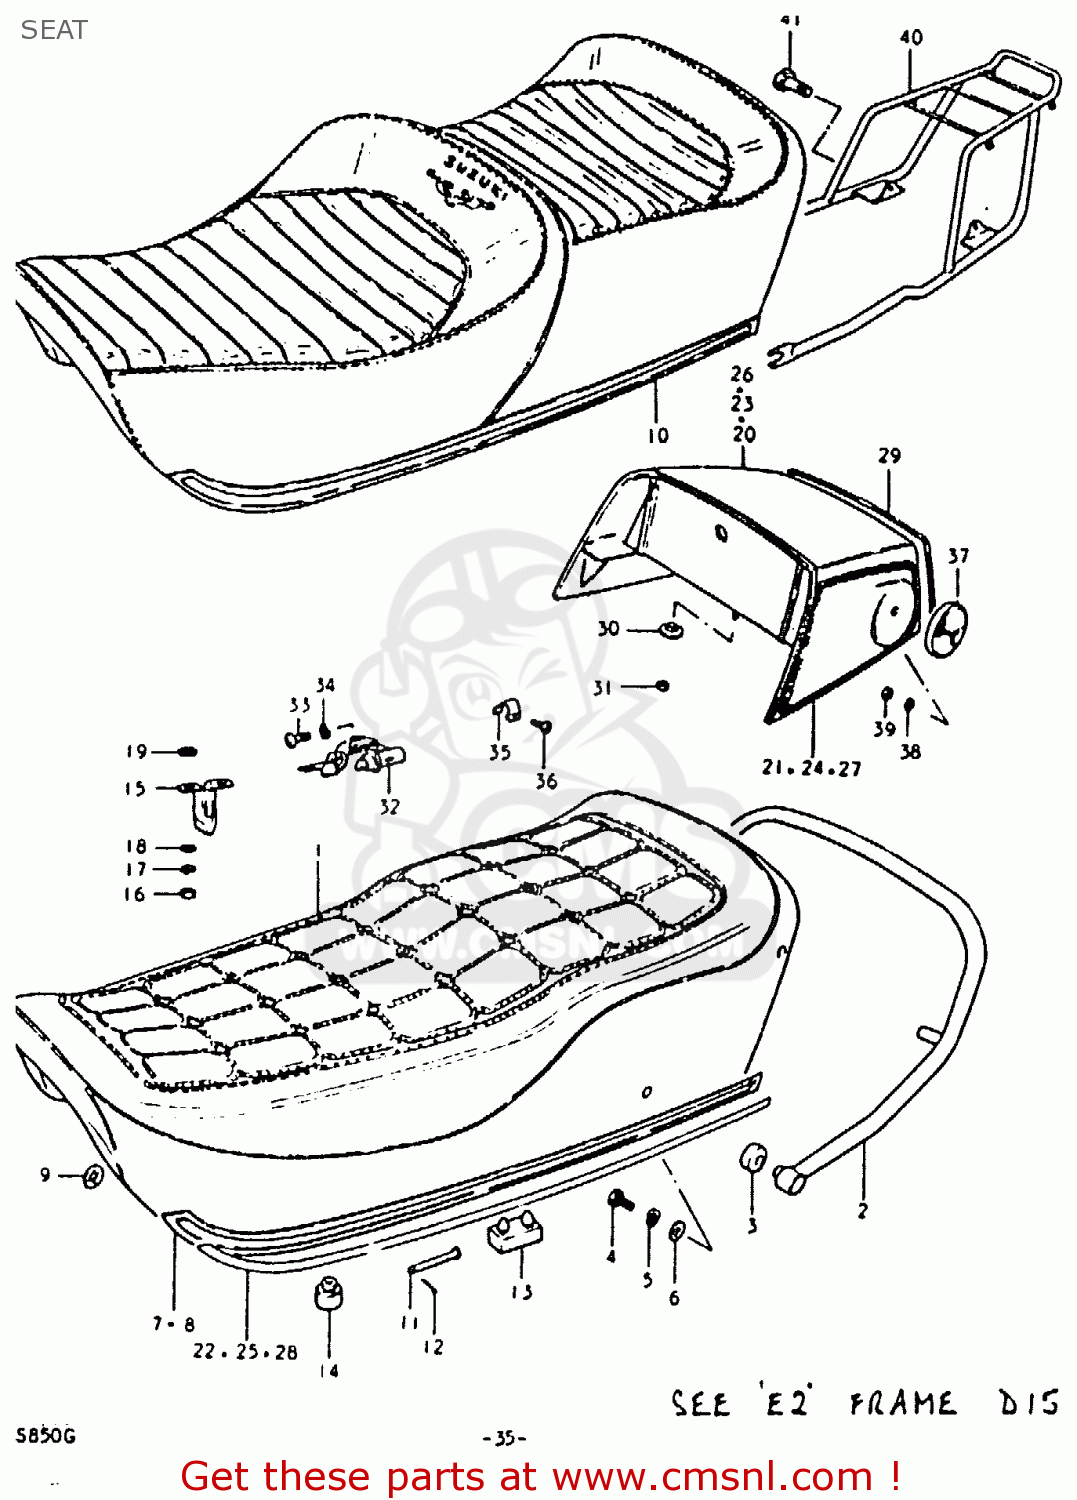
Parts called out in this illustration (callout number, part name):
1	SEAT ASSEMBLY
2	HANDLE,PILLION RIDER
3	CUSHION
4	BOLT
5	LOCK WASHER
6	WASHER
7	MOLE,R
8	MOLE,L
9	NUT
10	SEAT ASSEMBLY
11	PIN
12	PIN
13	CUSHION
14	CUSHION
15	STRIKER,SEAT LOCK
16	NUT
17	LOCK WASHER
18	WASHER
19	WASHER (6.5X20X1.2)
20	COVER, SEAT TAIL
21	TALL COVER TAPE SET
22	TAPE SET
23	COVER, SEAT TAIL
24	TAIL COVER TAPE SET
25	TAPE SET, SEAT MOULDING
26	COVER, SEAT TAIL
27	TAIL COVER TAPE SET
28	TAPE SET, SEAT MOULDING
29	MOLDING,SEAT TAIL COVER
30	WASHER
31	NUT 6MM
32	LOCK ASSY,SEAT
33	SCREW
34	LOCK WASHER
35	SPRING,HELMET HOLDER
36	SCREW
37	REFLEX REFLECTOR,RR
38	WASHER
39	NUT
40	CARRIER
41	BOLT
